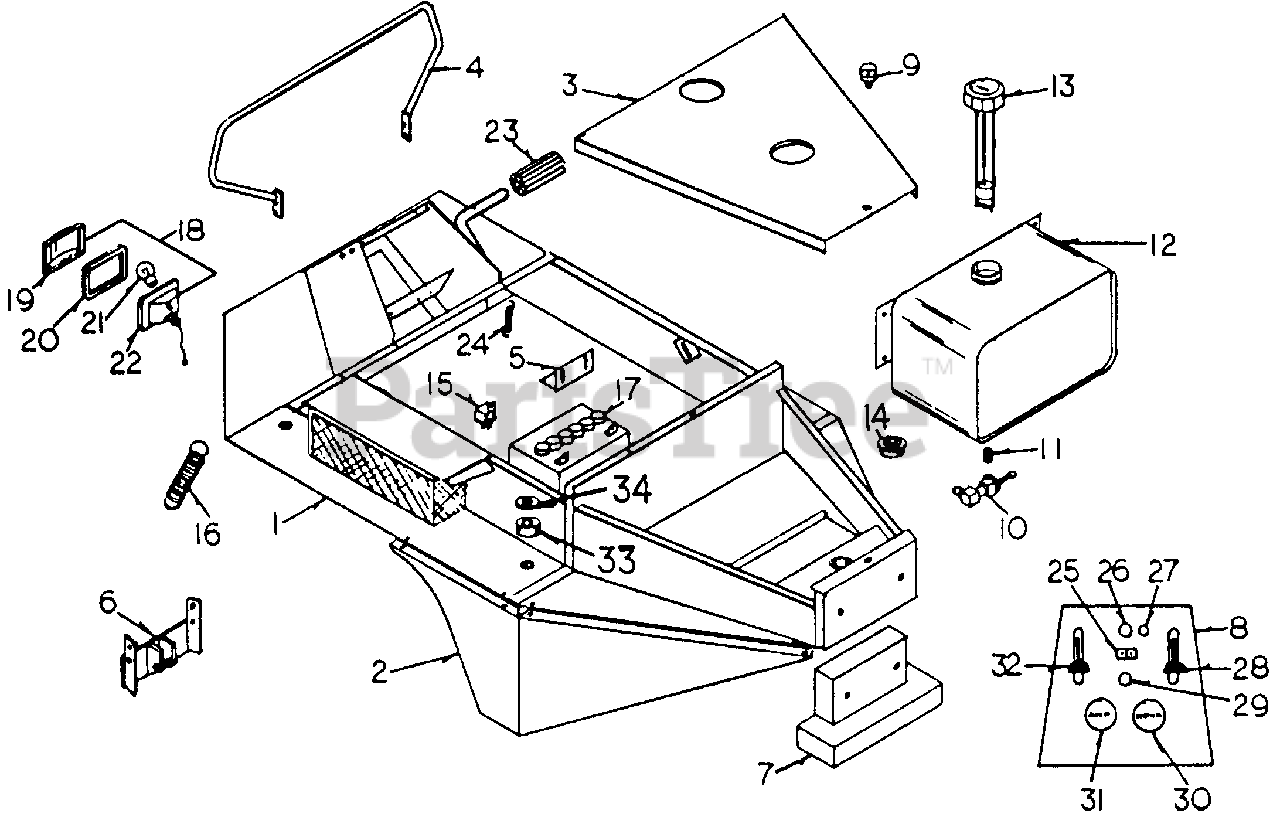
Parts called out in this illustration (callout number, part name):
2	Fender, LH
6	Top Cylinder Mount
10	Shut-off Valve
13	Fuel Tank Cap w/Gauge
15	Relay
18	Light Assembly
19	Lens
20	Casket
21	Bulb
23	Brake Pedal Pad
25	Light Switch
26	Clutch Switch
28	Throttle Cable
29	Ignition Switch
33	Rubber Body Mount
34	Body Mount Washer
